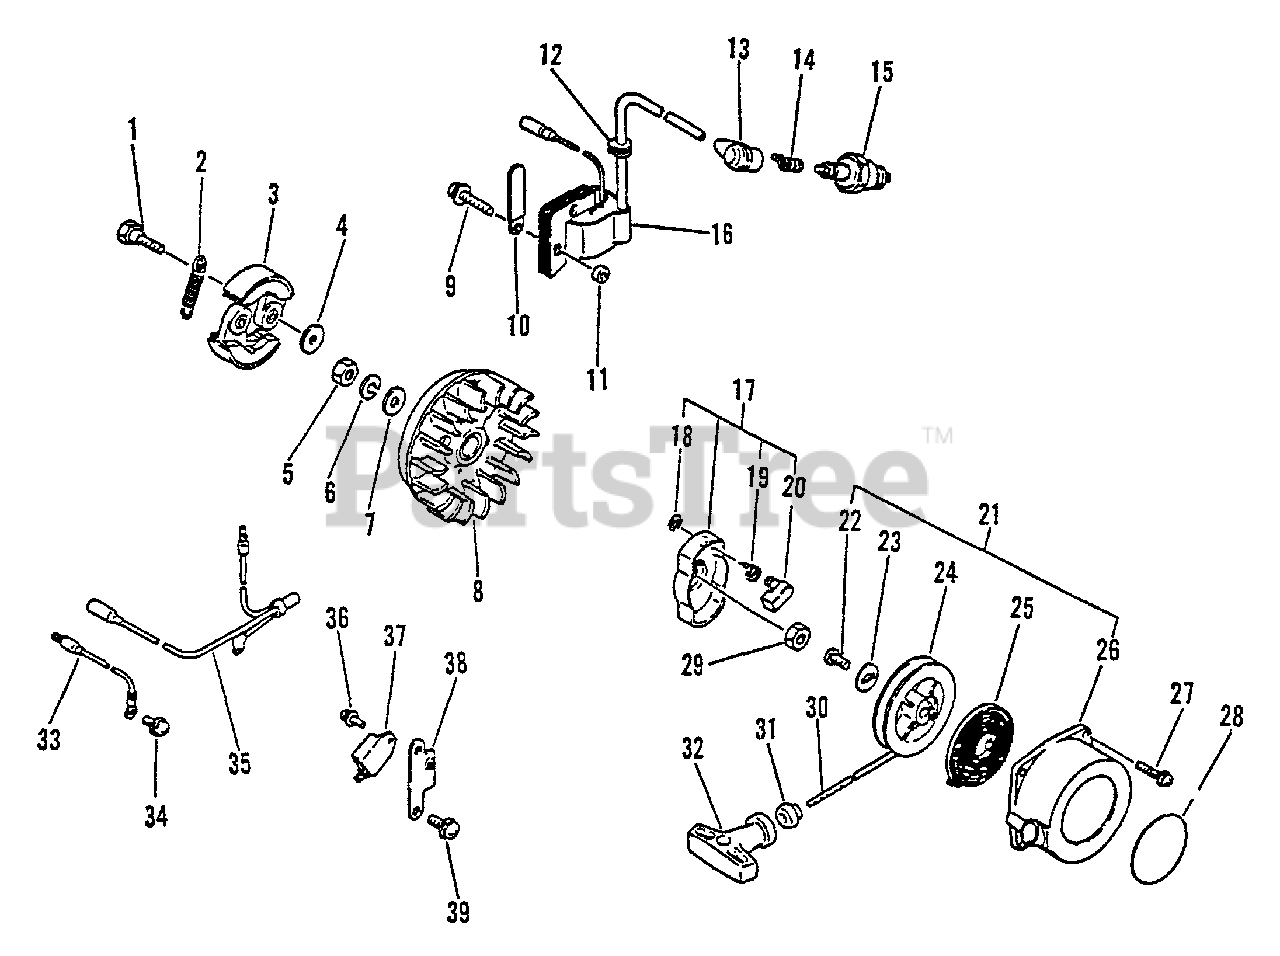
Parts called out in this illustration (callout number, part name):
1	BOLT, CLUTCH
2	SPRING, CLUTCH
3	SHOE, CLUTCH
4	WASHER 6.2×19×1.0
6	WASHER, SPRING 8
7	WASHER 8.2×17×1.6
8	FLYWHEEL
9	SCREW 5×25
11	WASHER 5.2×12×3
13	CAP, SPARK PLUG
14	TERMINAL, SPARK PLUG
15	SPARK PLUG - BPM7A
16	COIL, IGNITION
17	PAWL ASSY, STARTER
18	E-RING 4
19	SPRING, RETURN
20	PAWL, STARTER
21	STARTER ASSY
24	REEL, ROPE
25	SPRING, RECOIL
26	CASE, STARTER - ORANGE
27	SCREW 4×20
28	LABEL, ECHO
29	NUT 8×1.25
30	ROPE, STARTER 4.0×880
31	GUIDE, ROPE
32	GRIP, STARTER
33	LEAD - GROUND L= 115
34	SCREW 5×10
36	SCREW 4×8
37	COIL, IGNITION
38	BRACKET, IGNITION COIL
39	SCREW 5×12
